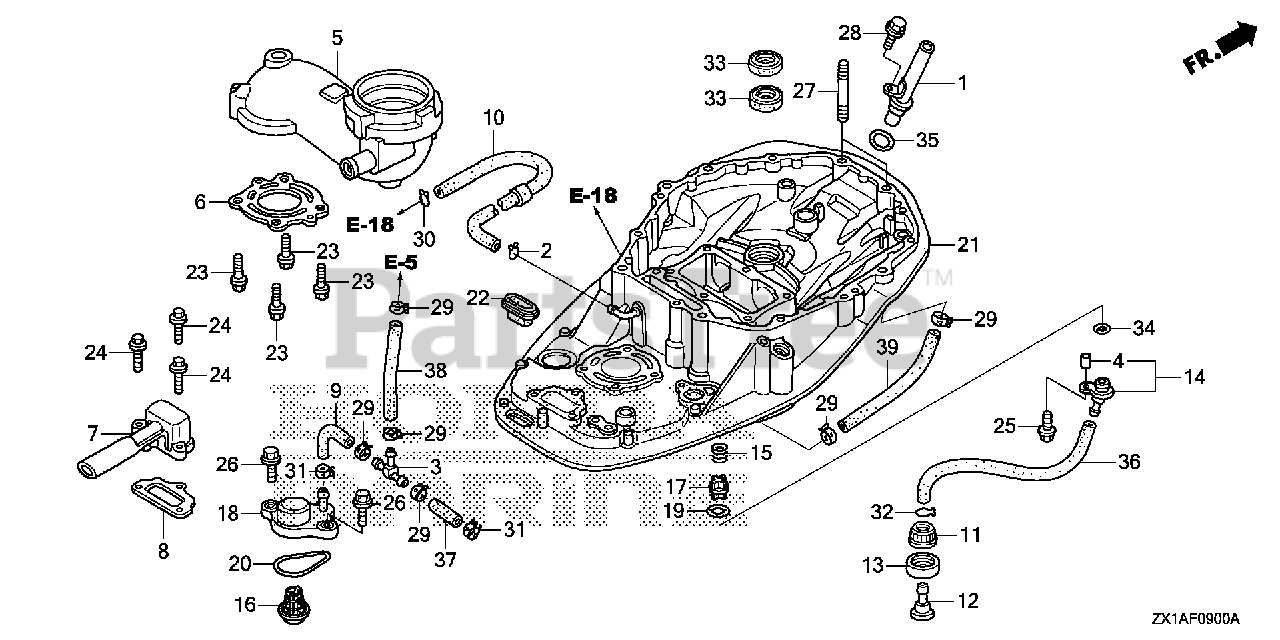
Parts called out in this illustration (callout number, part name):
1	PIPE, OIL LEVEL
2	CLIP, TUBE (ENGINE NO.)
4	COLLAR, DISTANCE (6.5X11X7.5)
5	GUIDE, EX. *NH8* (DARK GRAY)
6	GASKET, EX. GUIDE
7	PORT, IDLE EX.
8	GASKET, IDLE EX. PORT
9	TUBE, WATER RELIEF
10	TUBE F, WATER
11	NUT, WATER MOUTH
12	JOINT, WATER HOSE
13	SEAT, WATER MOUTH
14	COVER, FLUSH VALVE
14	COVER, FLUSH VLV
15	SPRING, FLUSH VALVE
16	VALVE ASSY., RELIEF
17	VALVE, FLUSH
18	COVER, RELIEF VALVE
19	GASKET, FLUSH VALVE
20	O-RING, THERMOSTAT COVER
21	CASE, MOUNT *NH8* (DARK GRAY)
22	RUBBER, MOUNT CASE SEAL
23	BOLT, FLANGE (8X30)
24	BOLT, FLANGE (6X25)
25	BOLT, FLANGE (6X16)
25	BOLT, FLANGE (6X20) (ENGINE NO.)
26	BOLT, FLANGE (6X22)
27	BOLT, STUD (10X55)
28	BOLT, FLANGE (6X12)
29	CLAMP, TUBE (D10.5) (ENGINE NO.)
30	CLIP, TUBE (B12)
31	CLAMP, TUBE (D10.5) (ENGINE NO.)
32	CLIP B1, TUBE
33	SEAL, WATER (22X35X7)
34	O-RING (16MM)
35	O-RING (11.5X3.5)
36	BULK HOSE, FUEL (8X1000) (95001-80001-(95001-80001-60M)
37	BULK HOSE, VACUUM (7X3000) (7X550)
38	BULK HOSE, VACUUM (7X3000) (7X550)
39	BULK HOSE, VACUUM (7X3000) (7X550)
